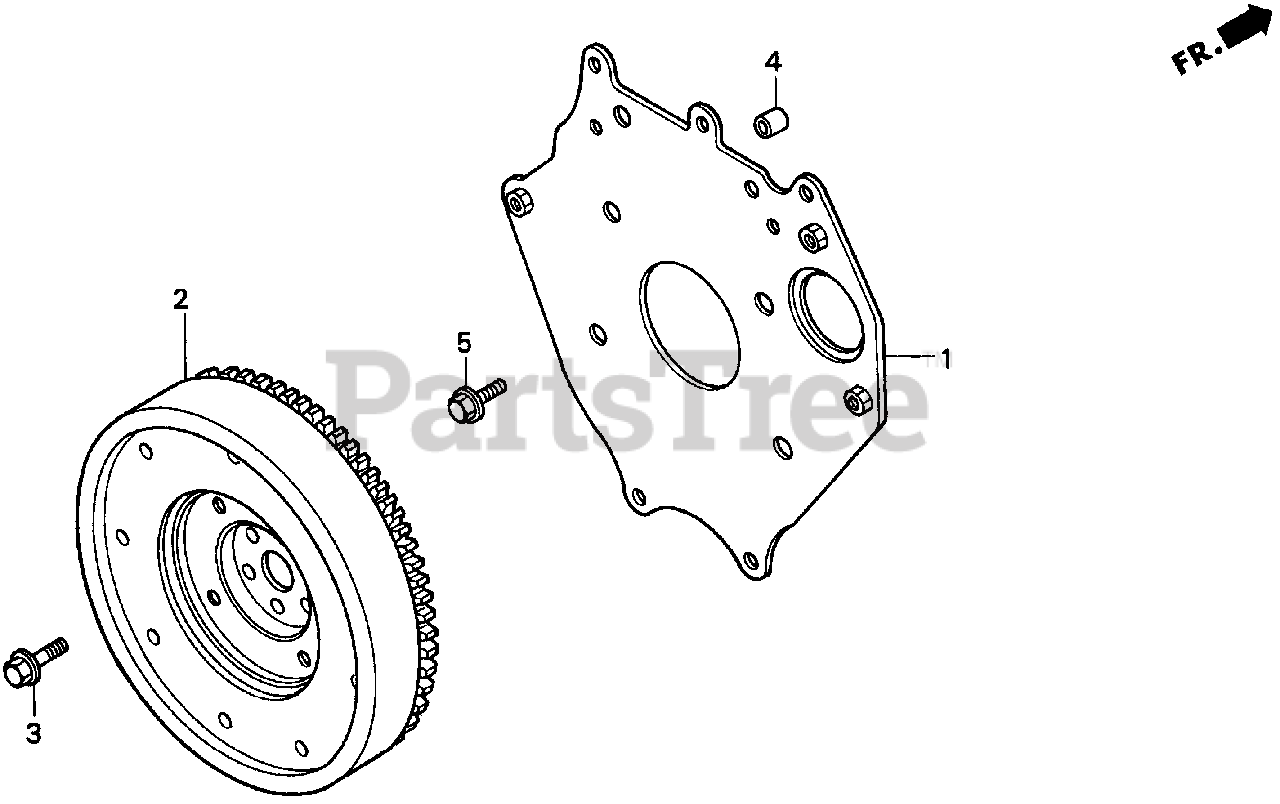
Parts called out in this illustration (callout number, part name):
1	PLATE, RR. END
3	BOLT (12MM)
4	PIN, DOWEL (14X10)
5	BOLT, FLANGE (12X28)
